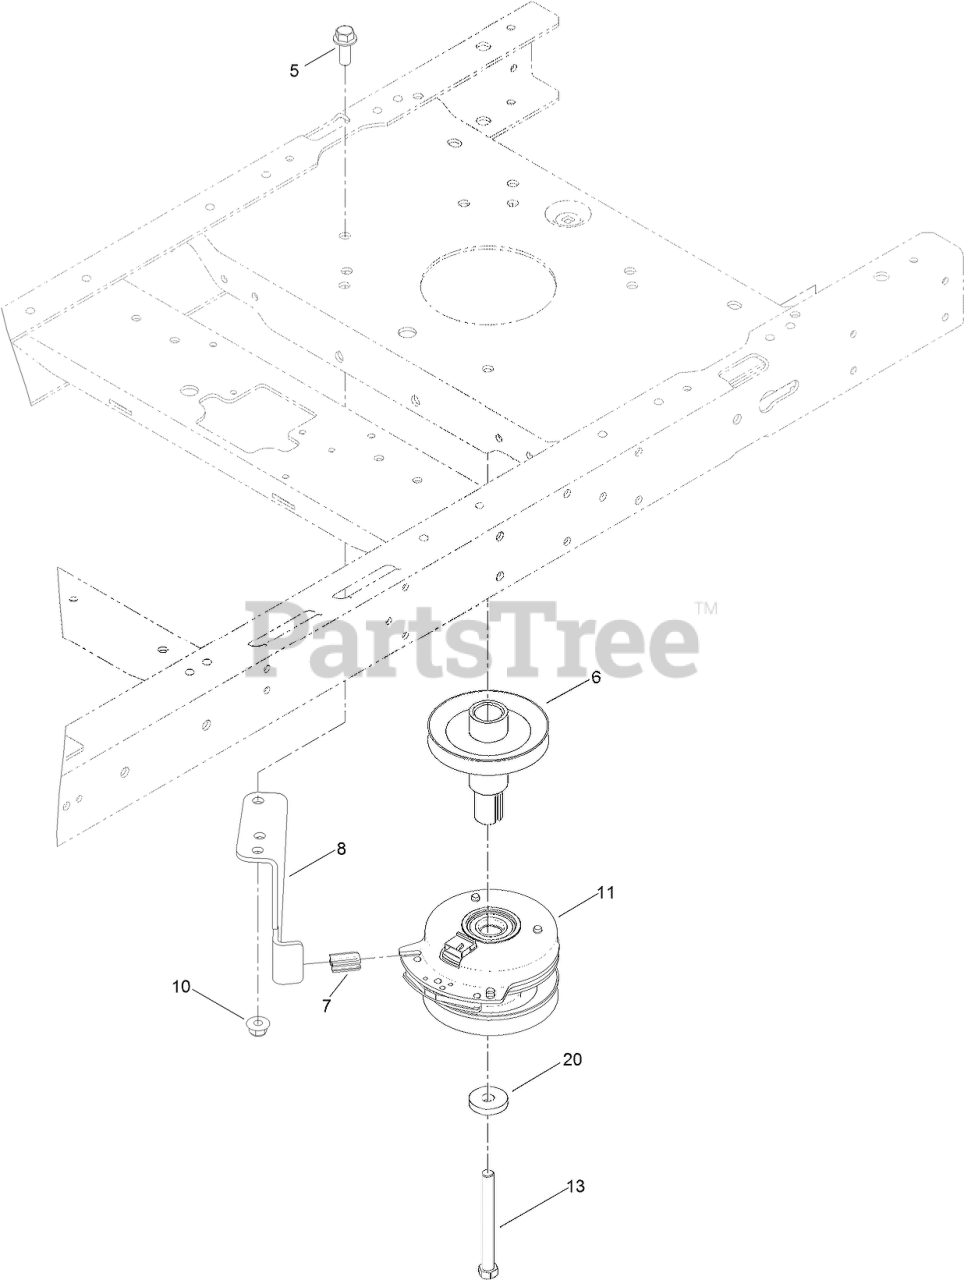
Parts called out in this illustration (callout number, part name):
5	SCREW-HHF
6	PULLEY-ENGINE
7	ISOLATOR-CLUTCH
8	STOP-CLUTCH
10	NUT-HF, NI
11	CLUTCH-PTO
13	SCREW-HH
20	WASHER
